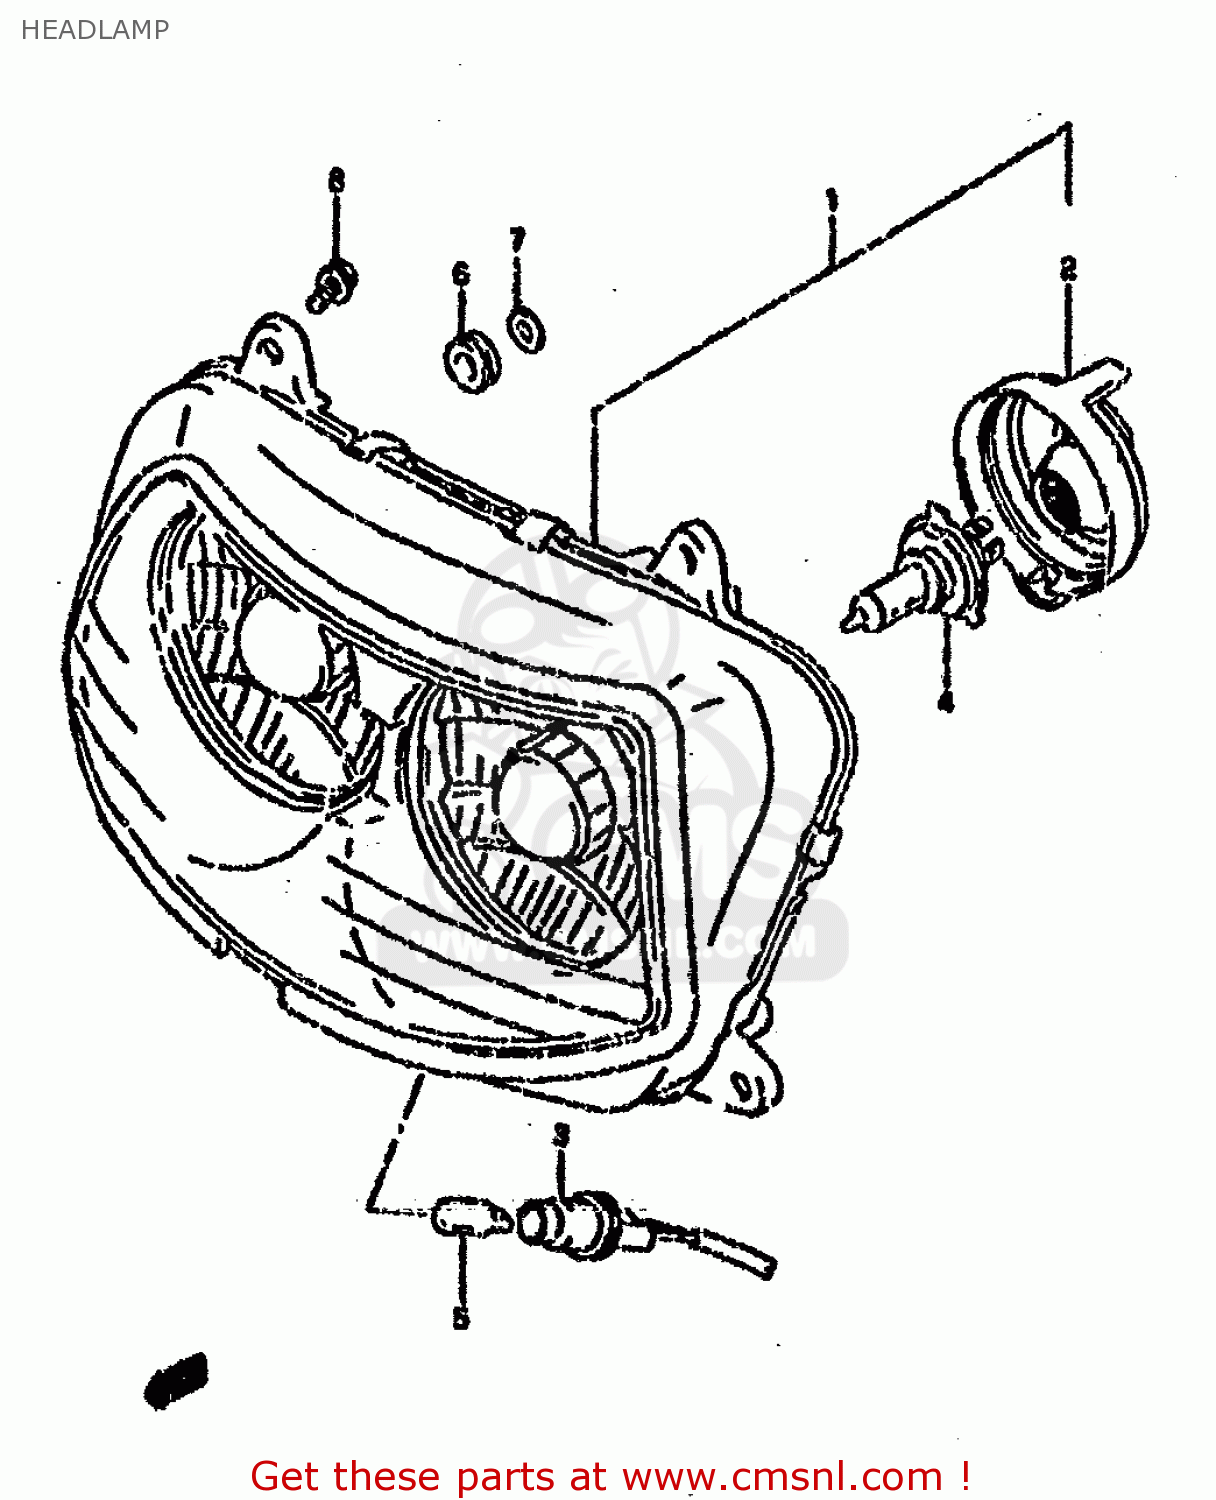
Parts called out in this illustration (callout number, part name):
1	HEADLAMP ASSY
2	COVER,SOCKET
3	SOCKET
4	BULB(12V60/55W,H4)
5	BULB(12V5W)
6	CUSHION
7	WASHER(5.5X16X1.2)
8	SCREW,SIDE HOL
